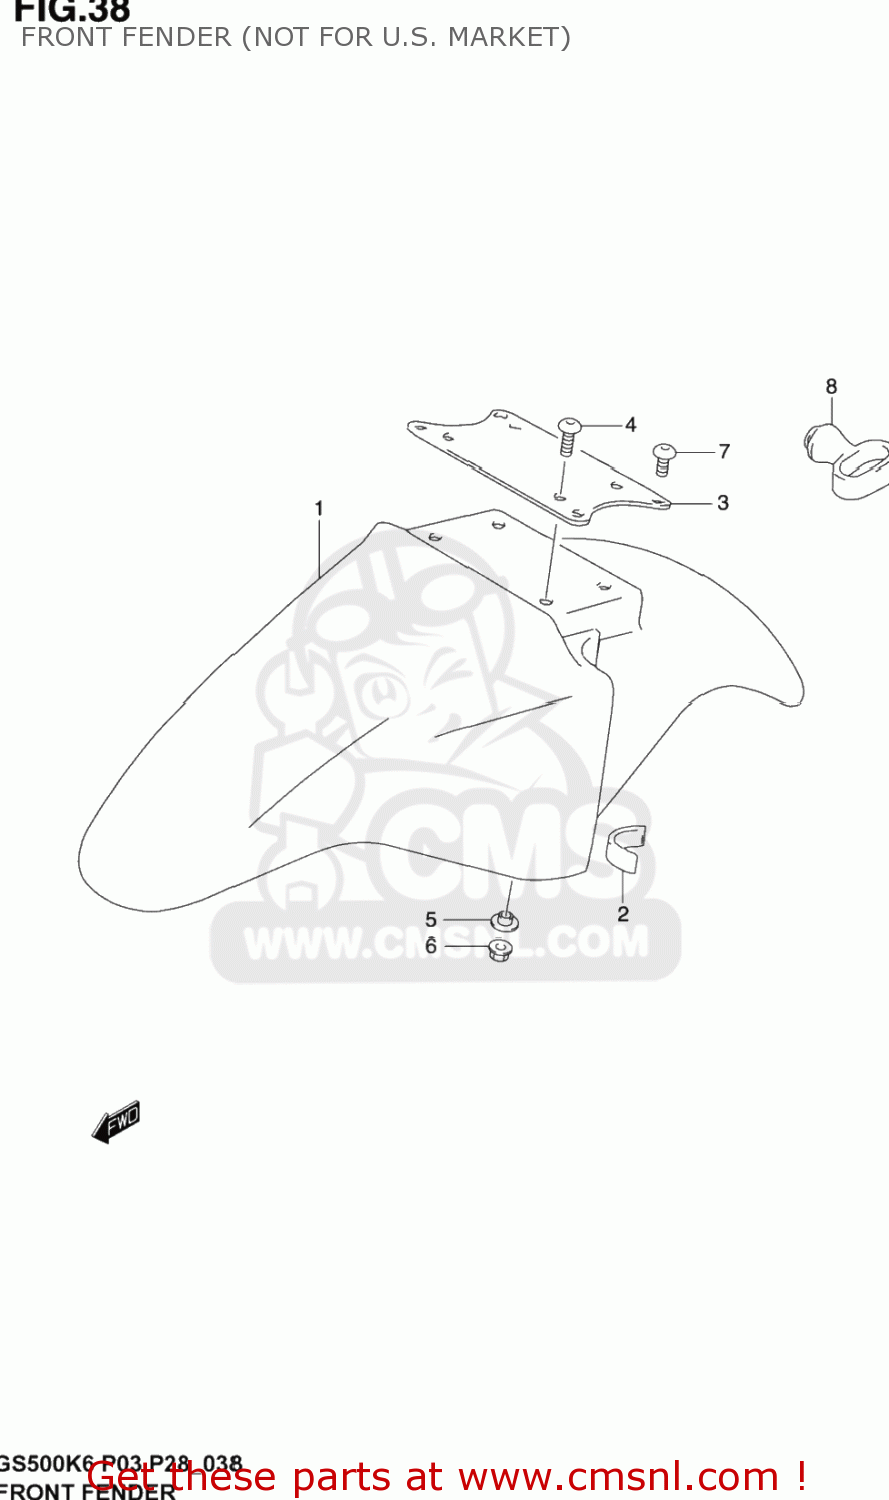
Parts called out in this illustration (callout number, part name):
1	FENDER,FRONT
2	CUSHION
4	SCREW(5X18)
5	WASHER
6	NUT
7	SCREW(6X12)
8	GUIDE,CABLE
